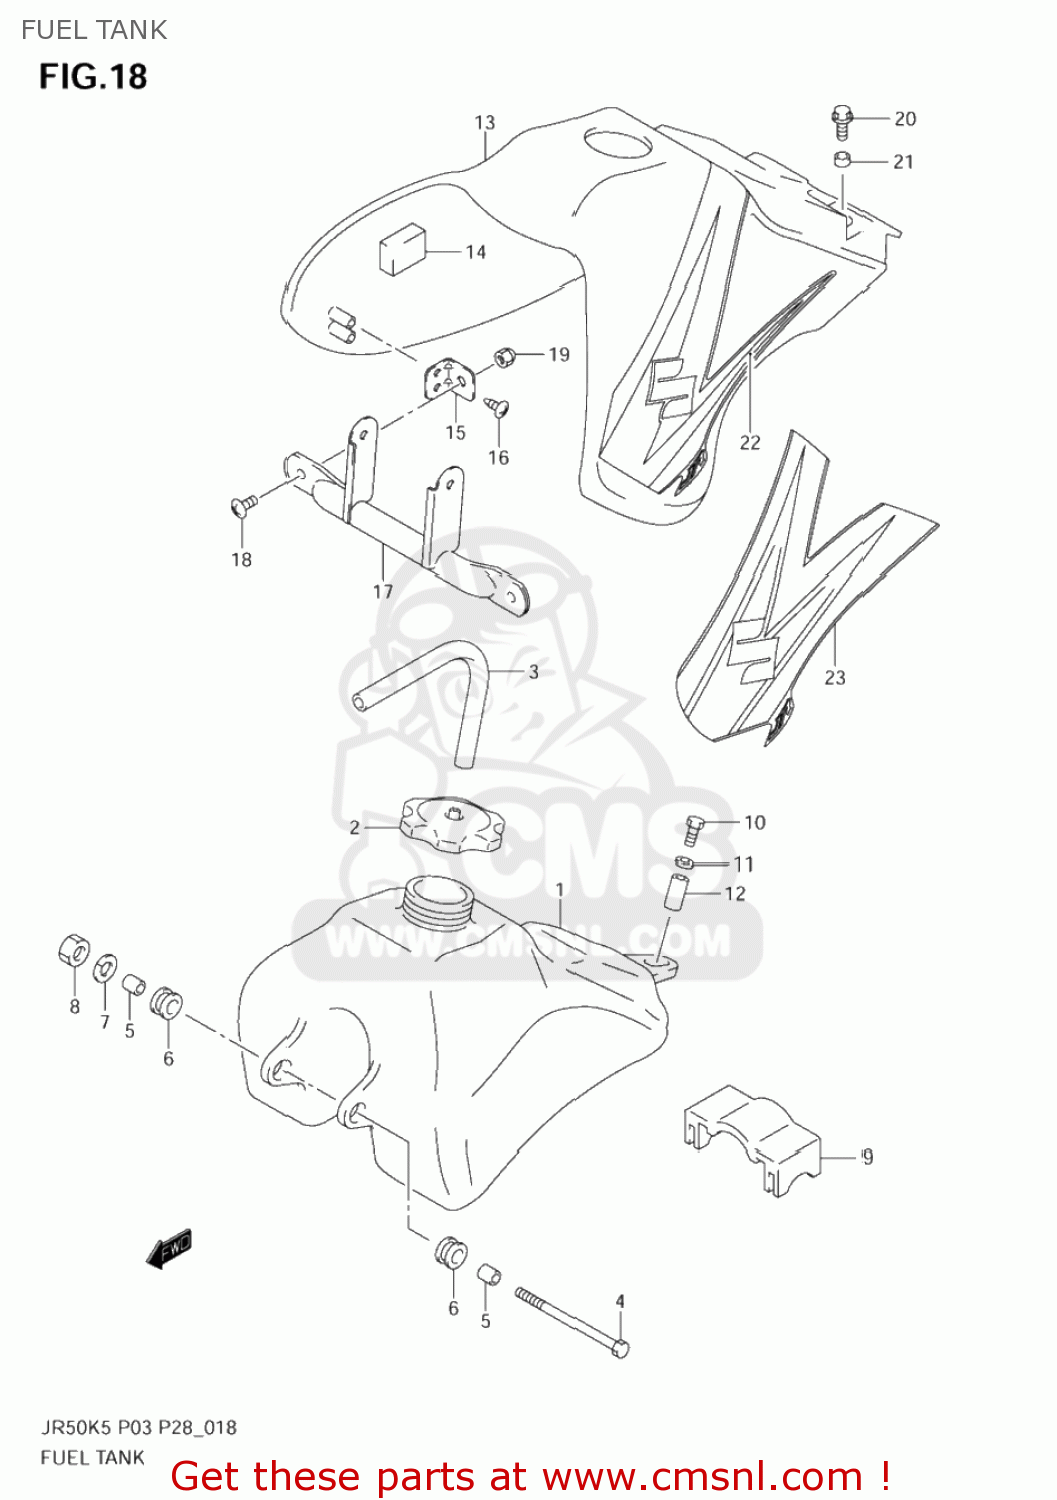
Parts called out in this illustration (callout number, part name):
1	TANK ASSY,FUEL
2	CAP ASSY,FUEL TANK FILLER
3	HOSE(5X8.2X600)
4	BOLT, FRONT
5	SPACER(6.5X10X11.5)
6	CUSHION
7	LOCK WASHER
8	NUT 6MM
9	CUSHION,FUEL TANK UPR
10	BOLT
11	WASHER(6.5X18X1)
12	SPACER(6.5X9X7.2)
13	COVER,FUEL TANK
14	CUSHION,RADIATOR COVER FR
15	BRACKET,FUEL TANK COVER NO.1
16	SCREW
17	BRACKET,FUEL TANK COVER
18	SCREW 6X12
19	NUT
20	SCREW(6X16)
21	SPACER(6.5X10X5)
22	TAPE SET,FUEL TANK COVER
23	TAPE SET,FUEL TANK COVER
